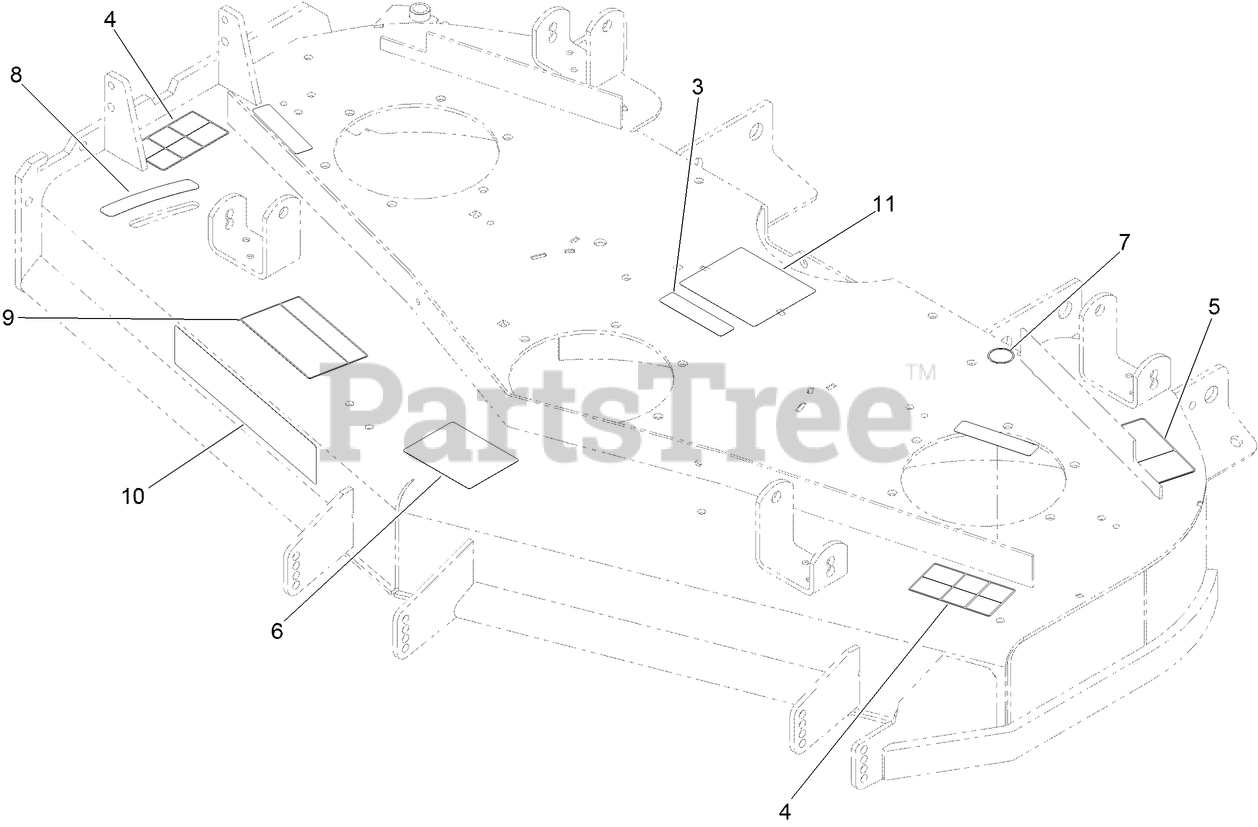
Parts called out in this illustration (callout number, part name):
3	DECAL-WARNING
4	DECAL-DANGER
5	DECAL-TORQUE, BLADE BOLT
6	DECAL-SCALP, ANTI
7	DECAL-GREASE
8	DECAL-SETTING, BAFFLE
9	DECAL-ADJUSTMENT, BAFFLE
11	DECAL-ROUTING, BELT
